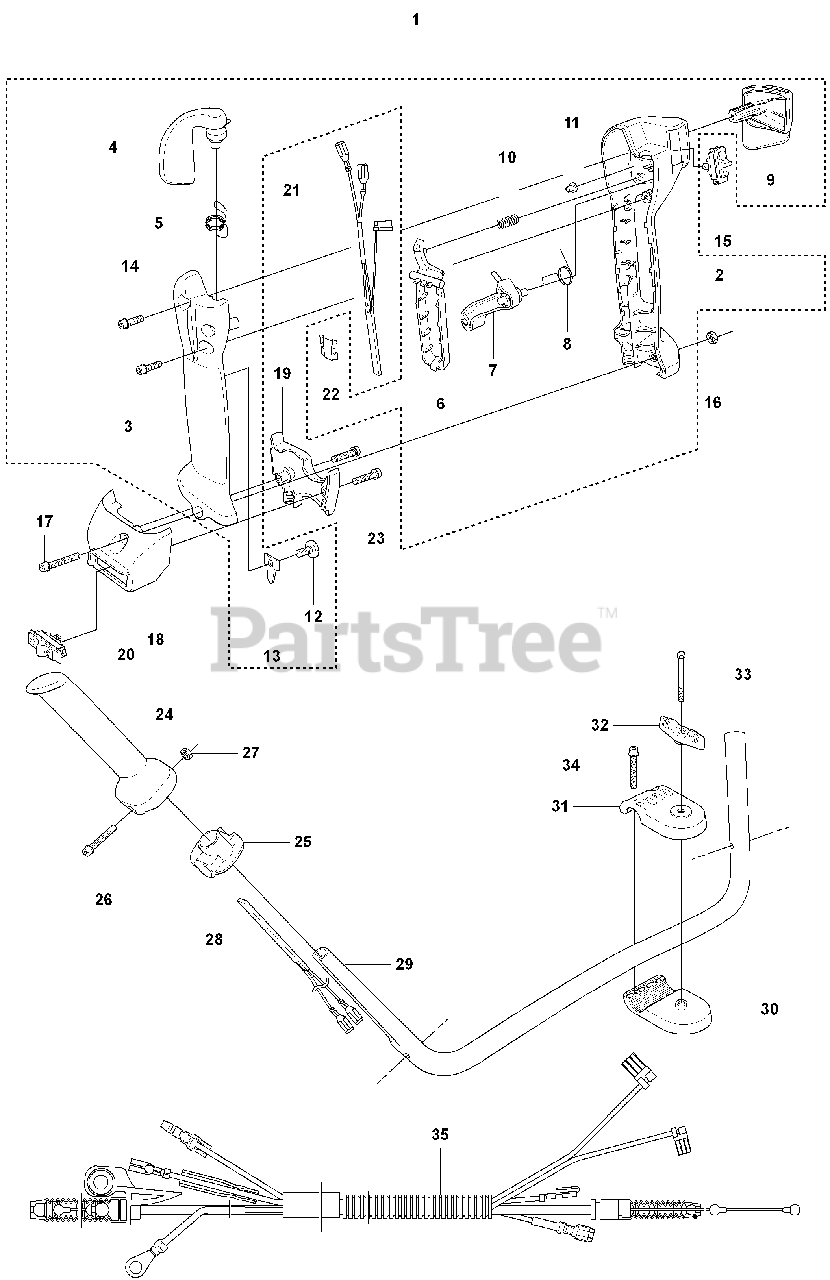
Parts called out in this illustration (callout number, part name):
2	HANDLE
3	HANDLE
4	THROTTLE TRIGGER
5	RP SPRING
6	THROTTLE LOCK
15	STOP BUTTON
16	NUT M6M M5
17	SCREW
18	HOLDER
19	HOLDER
20	SWITCH (G)
21	HEATING ELEMENT
23	SCREW
27	NUT M6M M5
28	HEATING ELEMENT
29	%HANDLE
30	HANDLE HOLDER LOWER
31	HANDLE HOLDER UPPER
33	%SCREW
35	WIRING
